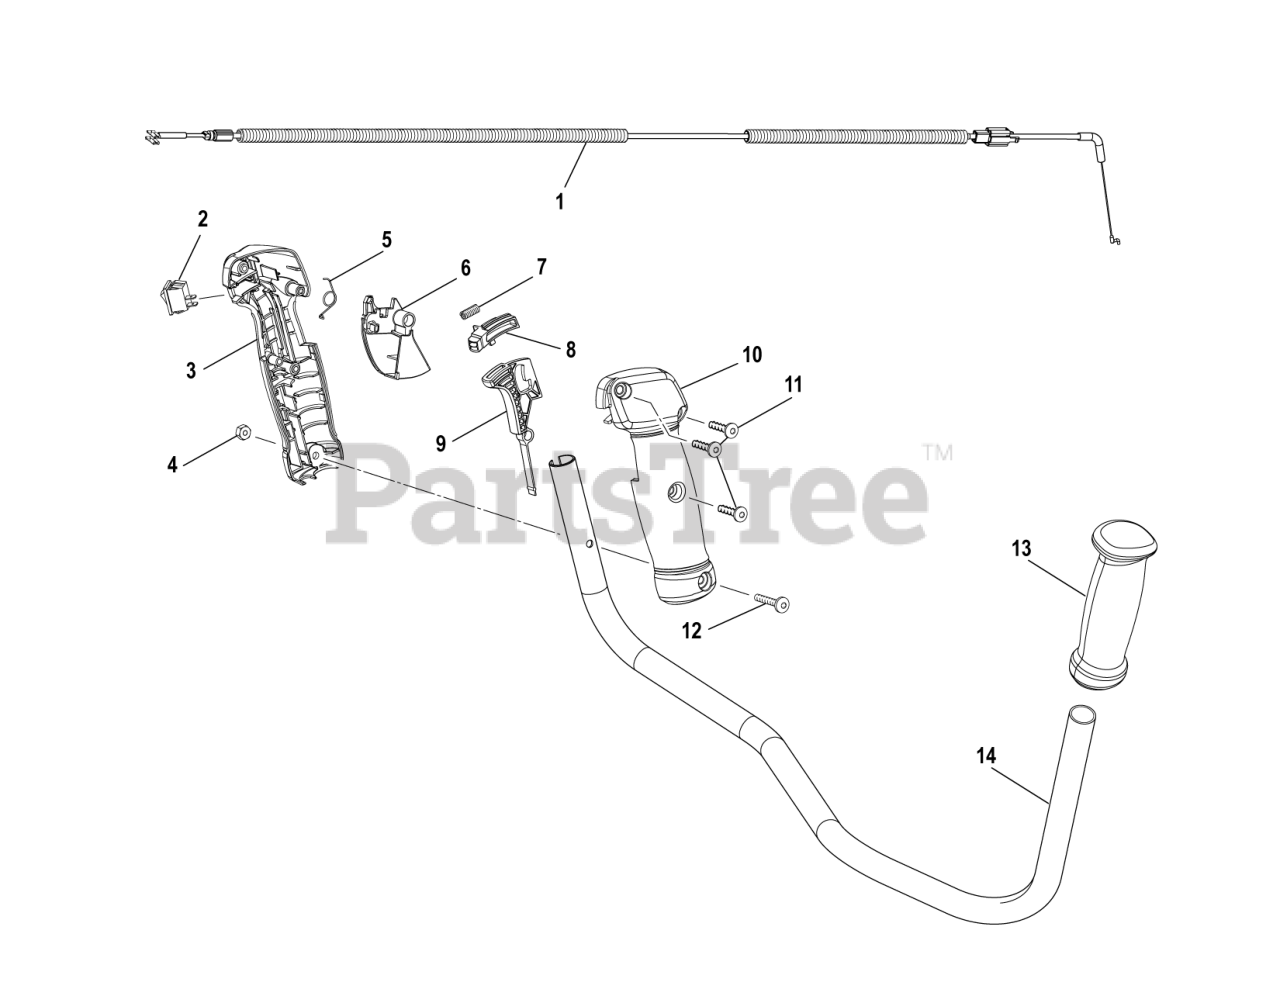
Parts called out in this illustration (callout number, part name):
1	ASSY., THROTTLE CABLE AND WIRE
2	SWITCH, STOP
3	COVER, TRIGGER HANDLE (LEFT)
4	NUT, LOCK
5	SPRING, TORSION
7	SPRING, COMPRESSION
8	BUTTON, THROTTLE (HALF)
9	LEVER, LOCKOUT
10	COVER, TRIGGER HANDLE (RIGHT)
13	GRIP, HANDLE
14	BAR, HANDLE
